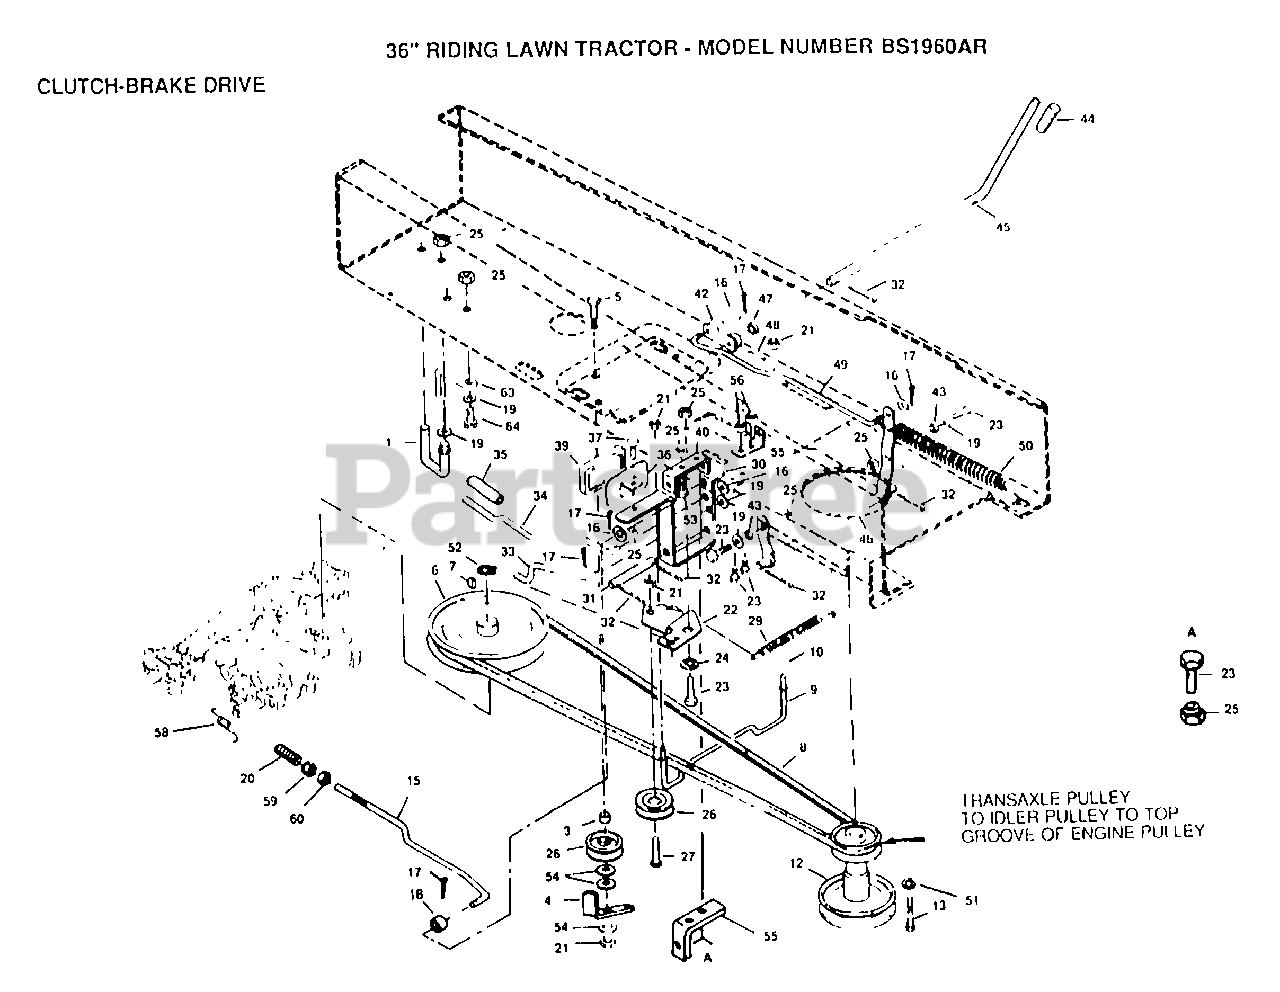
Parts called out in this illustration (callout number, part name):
1	BELT GUIDE T
4	BELT KEEPER T
6	PULLEY-TRANS T
9	MID BELT GUIDE LT
10	WASHER
13	BOLT RER
16	WASHER
18	WASHER
19	WASHER M
20	SPRING ROD LT
22	IDLER BRACKET
23	BOLT
29	IDLER SPRING
30	FOOT PEDAL LT
32	PIN COTTER 1/8
33	CLUTCH ROD
34	PARK BRK ROD T
36	PEDAL PLATE LT
37	BOLT
39	FOOT PAD LT
40	PEDAL BRACKET T
45	CLUTCH HANDLE L
49	BALDE ROD LT
51	LOCKWASHER
53	BOLT
54	WASHER
55	SWITCH BRKT
60	NUT
63	BELT RETAINER GT
64	BOLT
